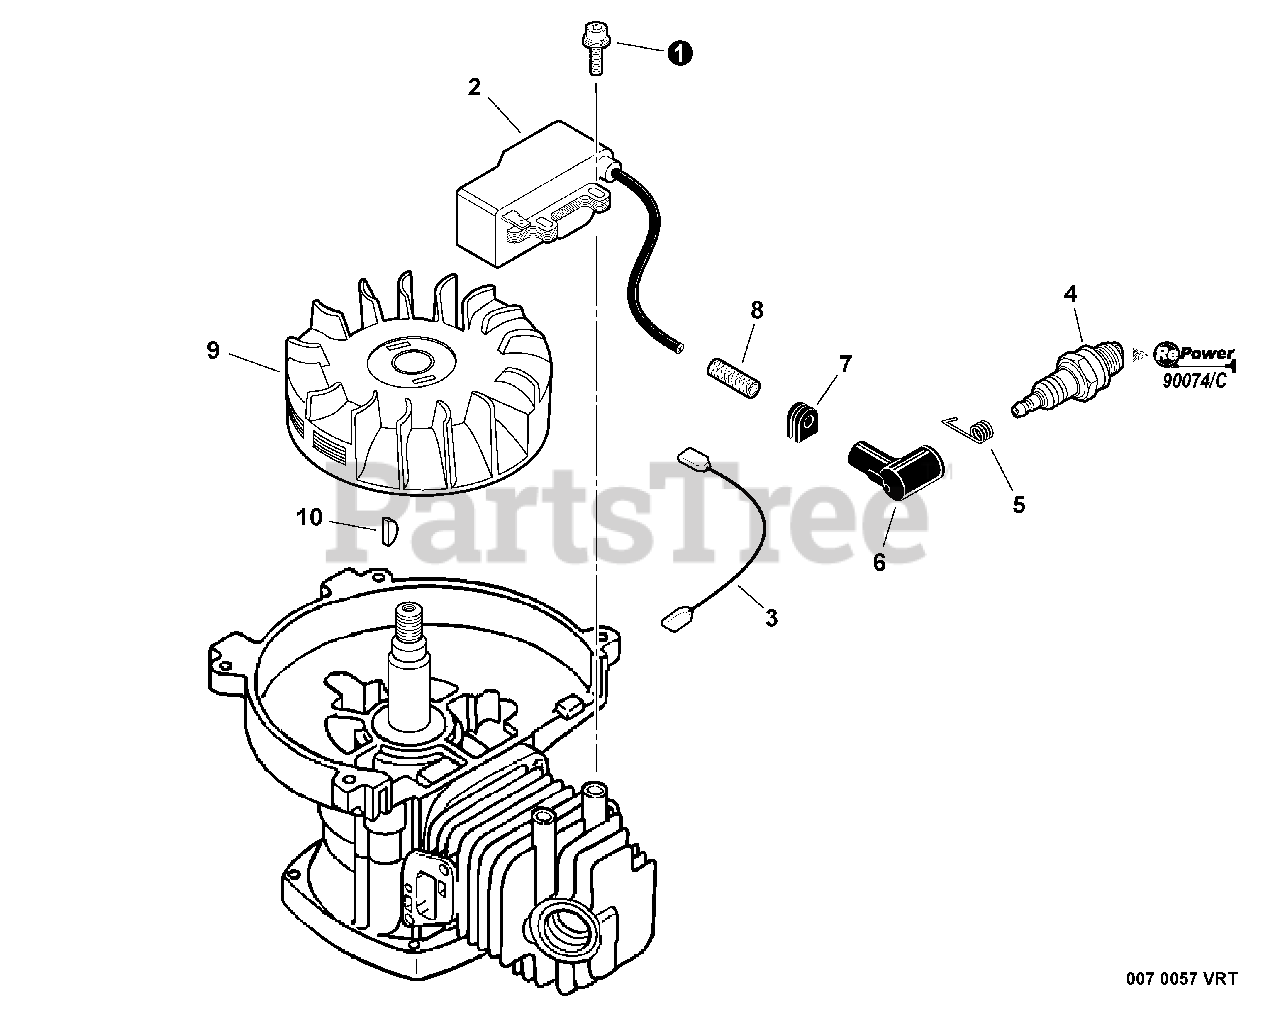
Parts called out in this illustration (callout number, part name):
1	SCREW - 4X20
2	COIL, IGNITION
3	LEAD - IGNITION
4	SPARK PLUG -- BPM-8Y
4	SPARK PLUG -- BPMR-8Y
5	TERMINAL, SPARK PLUG CAP
6	CAP, SPARK PLUG
8	TUBE, INSULATOR
9	FLYWHEEL
11	RePower TUNE-UP KIT
